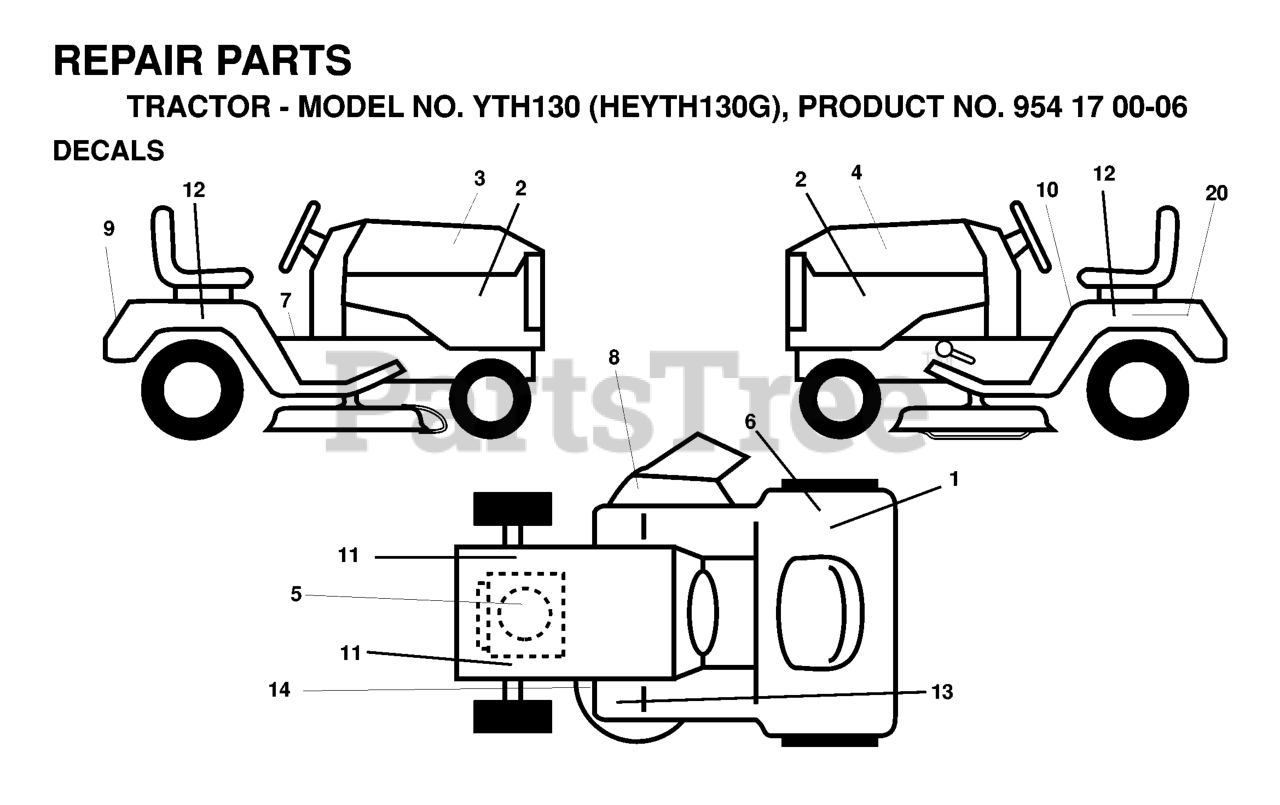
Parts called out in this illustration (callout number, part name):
1	DECAL CERTIFICATION
2	DECAL PNL SIDE
5	DECAL HP ENGINE
6	DECAL EUROPE STANDARD CE
7	DECAL PARK BRAKE
8	DECAL MOWER CUT/FINGER
9	DECAL FENDER HUSQ
10	DECAL READ OWNER'S MAN SYMS
11	DECAL
12	DECAL
13	DECAL
14	DECAL V BELT SCHEMATIC
20	DECAL BTRY SYMBOLS
